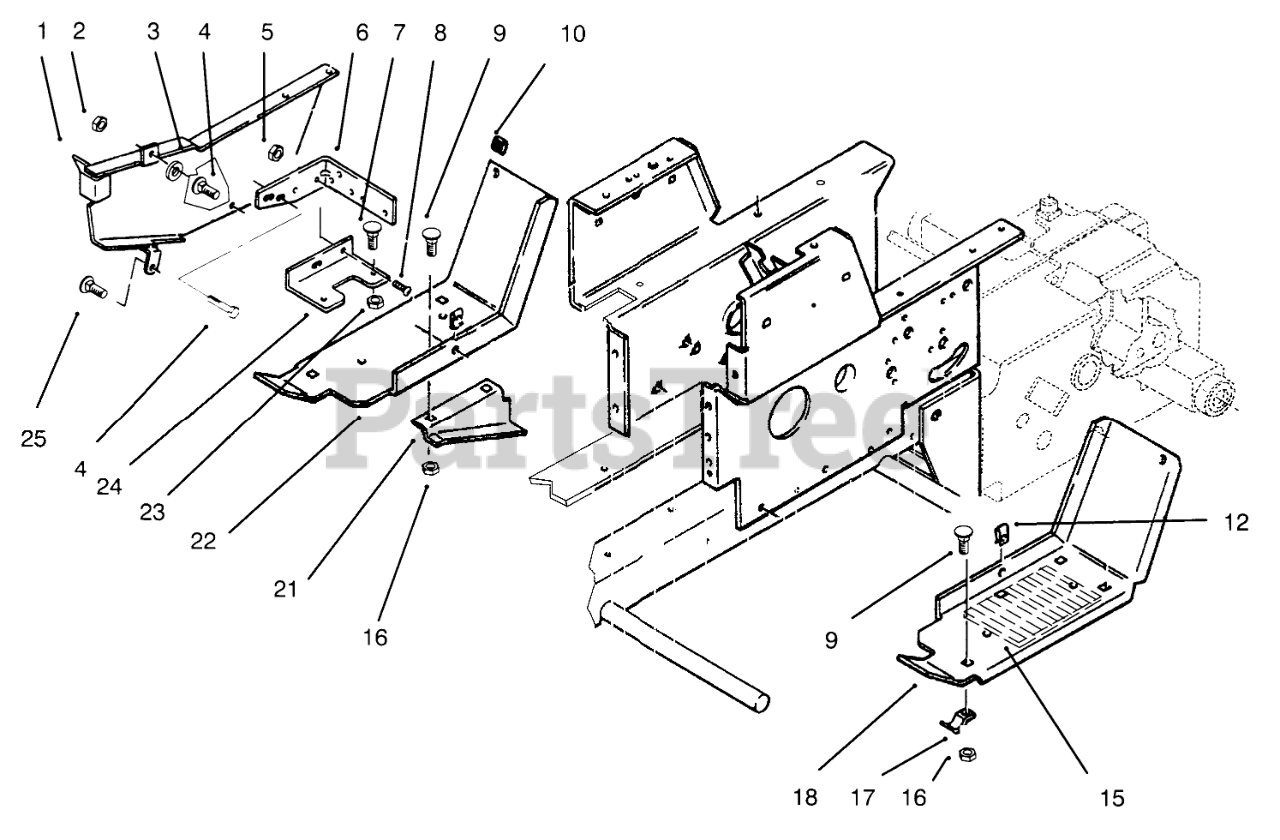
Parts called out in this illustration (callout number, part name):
1	Belt Guard
2	NUT-LOCK, NI
3	NUT-PUSH
4	BOLT-CARR
5	NUT-LOCK, NI
6	BRACKET-BELTB
8	SCREW-HH
9	BOLT-CARR
10	BUMPER
15	PAD-FOOTREST
16	NUT-LOCK, NI
17	BRACKET
18	FOOTREST LH R
21	GUID-LOWER BLTR
22	Footrest-RH
23	Nut
24	FUSE HOLDERB
25	SCREW
